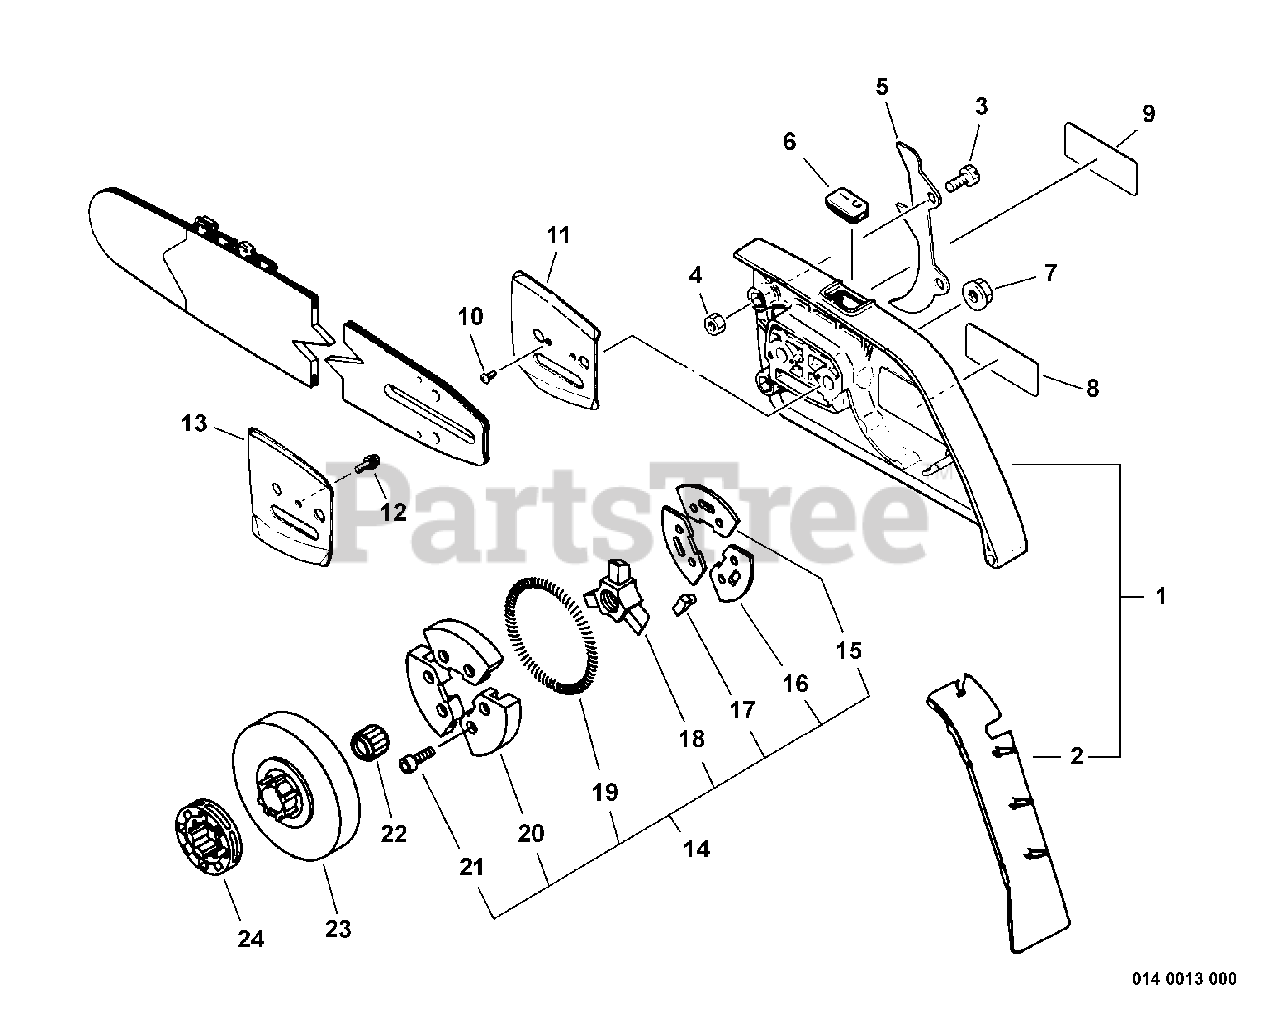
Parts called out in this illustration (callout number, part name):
1	GUARD, SPROCKET
1	SPROCKET GUARD KIT - ORANGE
7	NUT - FLANGE
8	LABEL - ECHO
9	LABEL - WARNING
10	SCREW - 3X6
11	PLATE, GUIDE - OUTER
12	SCREW - 4X8
13	PLATE, GUIDE - INNER
14	CLUTCH ASSY
15	PLATE, CLUTCH
16	PLATE, CLUTCH
17	PLATE, SPRING
18	HUB, CLUTCH
19	SPRING, CLUTCH
20	CLUTCH SHOE SET
21	SCREW - 4X8
22	BEARING, NEEDLE
23	DRUM, CLUTCH
24	SPROCKET, RIM
